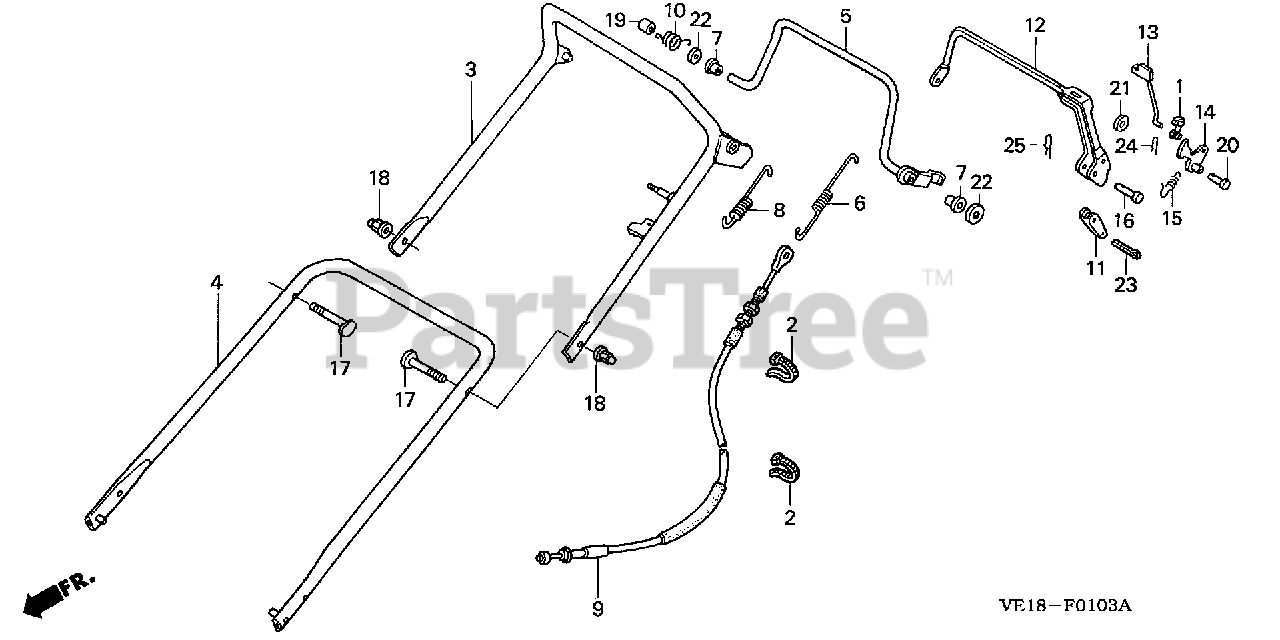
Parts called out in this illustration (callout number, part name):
1	JOINT, ROD
2	TIE, CABLE (157.5MM)
3	PIPE, HANDLE (UPPER) *NH105* (MAT BLACK)
4	HANDLE (LOWER) *NH105* (MAT BLACK)
5	LEVER, CLUTCH
6	SPRING, CLUTCH
7	BUSH, CLUTCH LEVER
8	SPRING, CLUTCH LEVER RETURN
9	CABLE, ROTO-STOP
10	SPRING, R. STOP RETURN
11	ARM, ROTO-STOP CABLE
12	LEVER, ROTO-STOP
13	ROD, RATCHET PUSH
14	LEVER, LOCK
15	SPRING, RATCHET RETURN
16	PIN, CLUTCH LEVER
17	BOLT, HANDLE HOLDER (8X36)
18	NUT, CAP (8MM)
19	COLLAR (8X11X13.5)
20	PIN, LOCK LEVER HINGE (6X30)
21	WASHER, PLAIN (6MM)
22	WASHER, PLAIN (8MM)
23	PIN, SPLIT (2.0)
24	PIN, LOCK (6MM)
25	PIN, LOCK (8MM)
